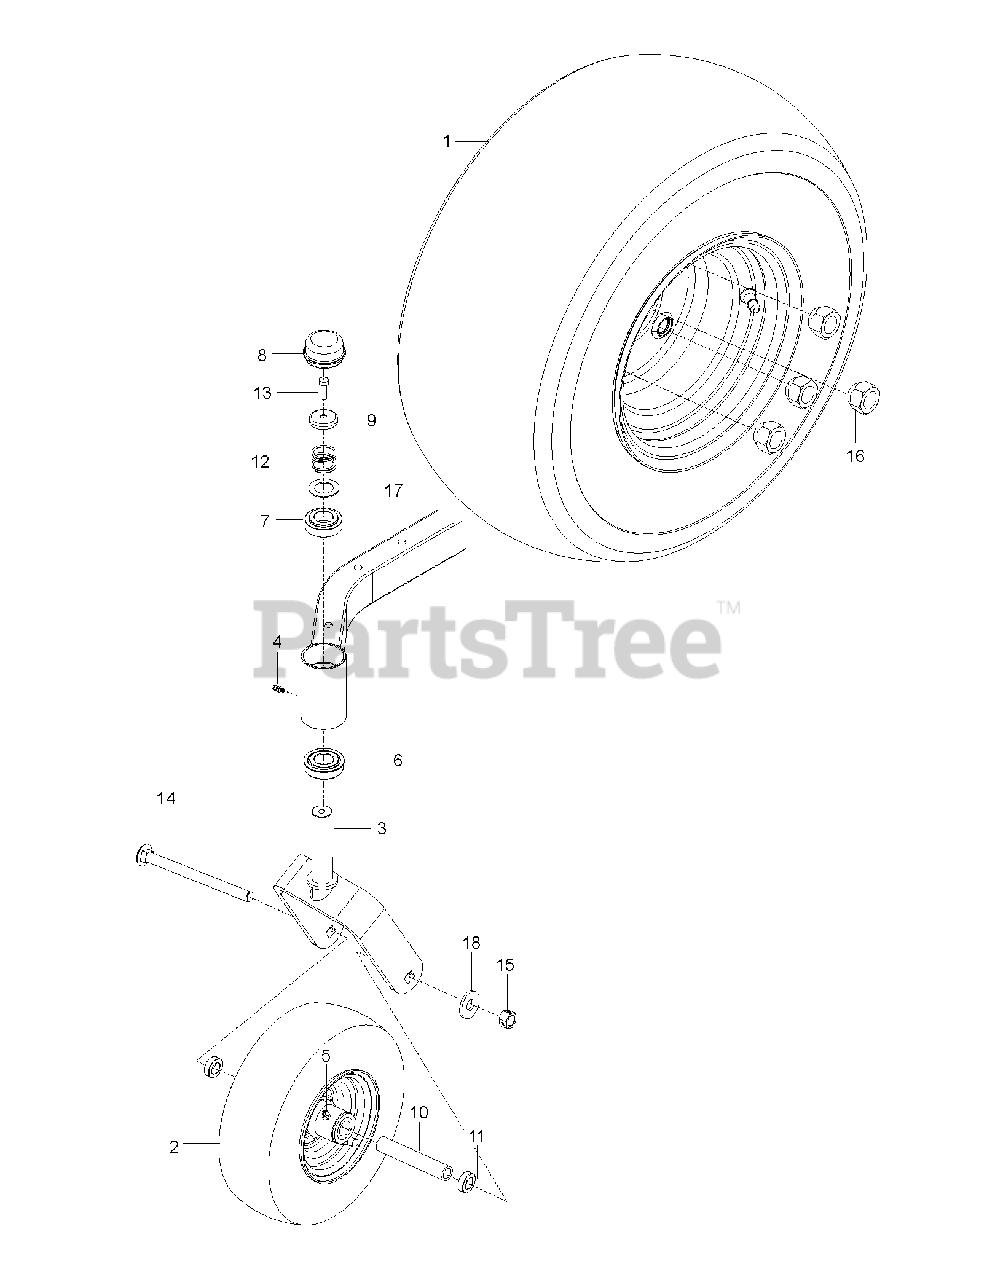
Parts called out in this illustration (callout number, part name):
1	Wheel, Carlstar 18 X 8.5-8"
2	Wheel, Carlstar 11 X 4-5"
3	YOKE.CASTER.ORANGE
4	ZERK, 3/16, DRIVE IN
5	ZERK
6	BEARING FLANGED
7	BUSHING, CASTER
8	GREASE CAP
9	CASTER.PLUG
10	SPACER SPLIT
11	SPACER 5/16"
12	SPRING, CASTER
13	5/16-18X1 HHB G5W/NY
14	RHSNB 1/2-13 X 7.5
15	NUT 1/2-13 HEX CNTRLK GR 5 ZD
16	LUG NUT 1/2F
17	WASHER, 1.025 ID X 1.64
18	WASHER.9/16 X 1 3/8 X 12 GA.
